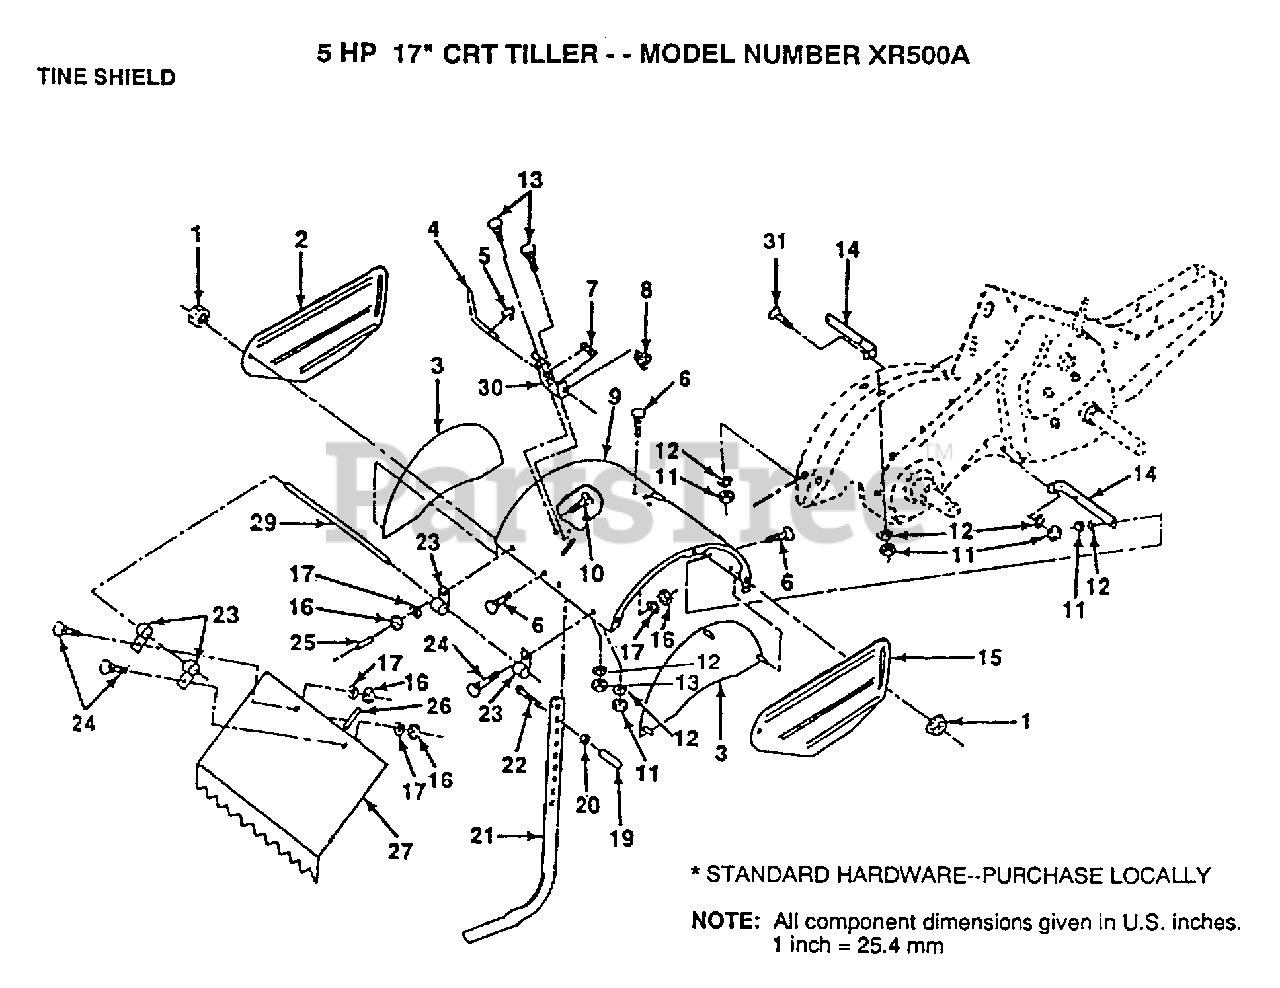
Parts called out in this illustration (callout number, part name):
1	NUT
3	"SHIELD,SIDE TI"
4	STAKE PIN TI
5	KLIP RING TI
6	BOLT
7	SPRING TI
8	SPRING CRT
9	"SHIELD,TINE TI"
10	BOLT
11	NUT.HEX.5/16-18
12	LOCKWASHER
13	BOLT CRT
14	BRKT SHIELD TINE
17	LOCKWASHER
19	GRIP CRT
20	NUT.HEX.3/8-16UNC
22	BOLT
23	HINGE CRT
24	BOLT
25	VINYL CAP TI
26	PAD IDLER TI
27	"SHIELD, LEVEL TI"
29	PIN HINGE
30	LATCH BRACKET TI
31	BOLT
